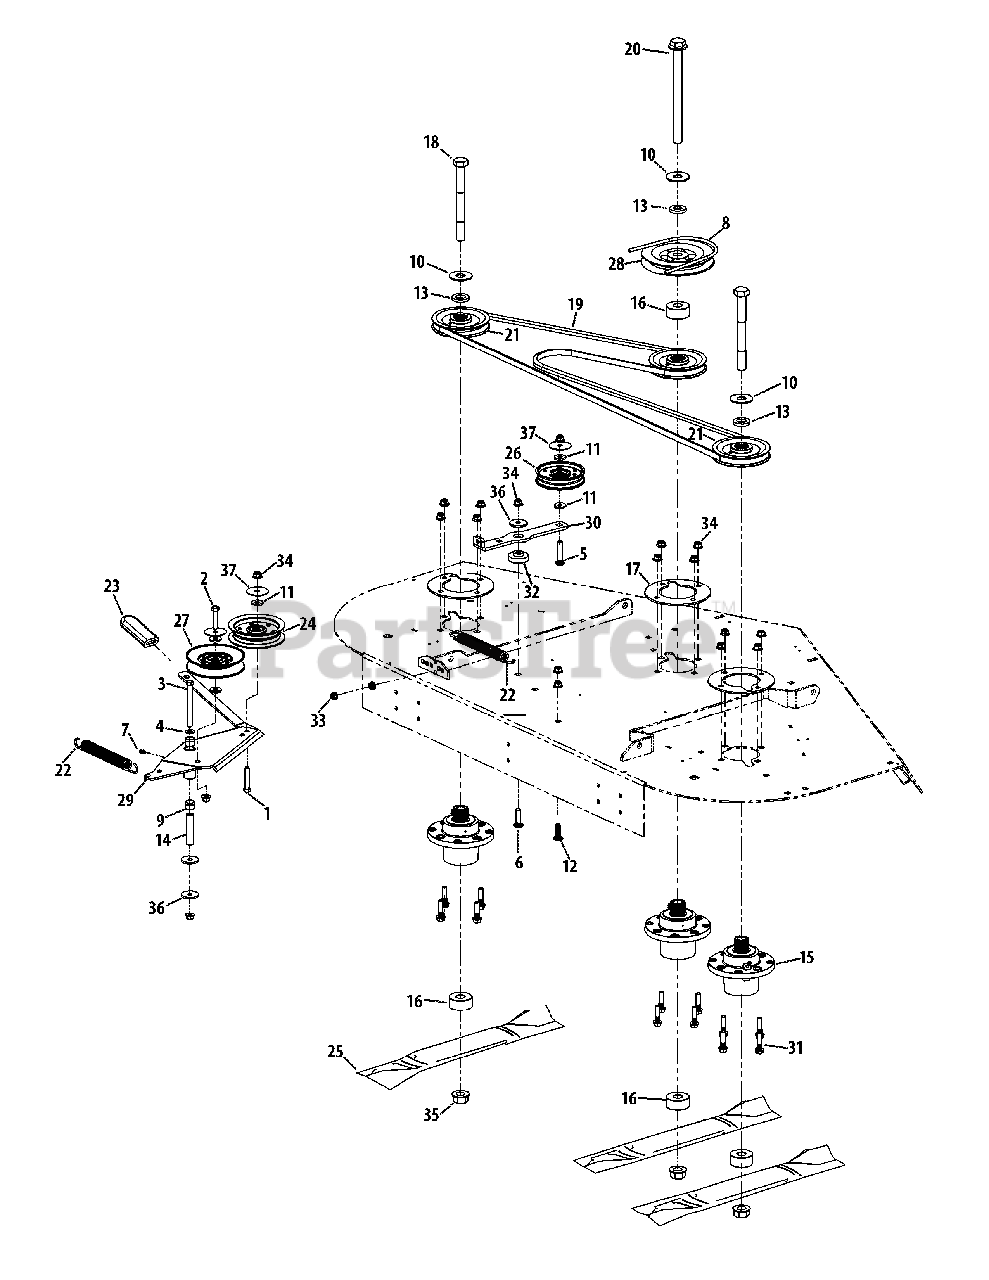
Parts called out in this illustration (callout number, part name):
1	Hex Screw, 3/8-16 x 2.00
2	Hex Screw, 3/8-16 x 1.75
3	Hex Screw, 3/8-16 x 4.00
4	Washer, .406 x .813 x .063
5	Carriage Bolt, 3/8-16 x 2.00
6	Carriage Bolt, 3/8-16 x 1.50
7	Grease Fitting, 1/4-28
8	V-Belt, PTO
9	Sleeve Bearing, .628 x .753 x .625
10	Washer, .781 x 2.00 x .105
11	Washer, .406 x 1.00 x .105
12	Carriage Bolt, 3/8-16 x 1.25
13	Spacer, .812 x 1.47 x .218
14	Spacer, .390 x .635 x 2.75
15	Spindle Assembly
16	Spacer, .760 x 2.00 x .925
17	Spindle Support Plate
18	Hex Screw, 3/4-16 x 7.00
19	V-Belt, Deck
20	Hex Screw, 3/4-16 x 9.00
22	Extension Spring, .94x 7.57 x .14
23	Flat Grip, 1.0 x 3.2 x .25
24	Idler Pulley
25	Hi-Lift Blade, 21.0
26	Idler Pulley
27	Idler Pulley
29	Double Idler Weldment w/ Handle
30	Deck Idler Arm
31	Carriage Bolt, 5/16-18 x 1.50
32	Flange Bolt, 3/8-16 x 1.5
33	Flange Lock Nut, 5/16-18
34	Flange Lock Nut, 3/8-16
35	Flange Lock Nut, 3/4-16
36	Flat Washer, .390 x 1.500 x .134
37	Flat Washer, .406 x 1.92 x .060
38	Shoulder Spacer, .854 x .280
